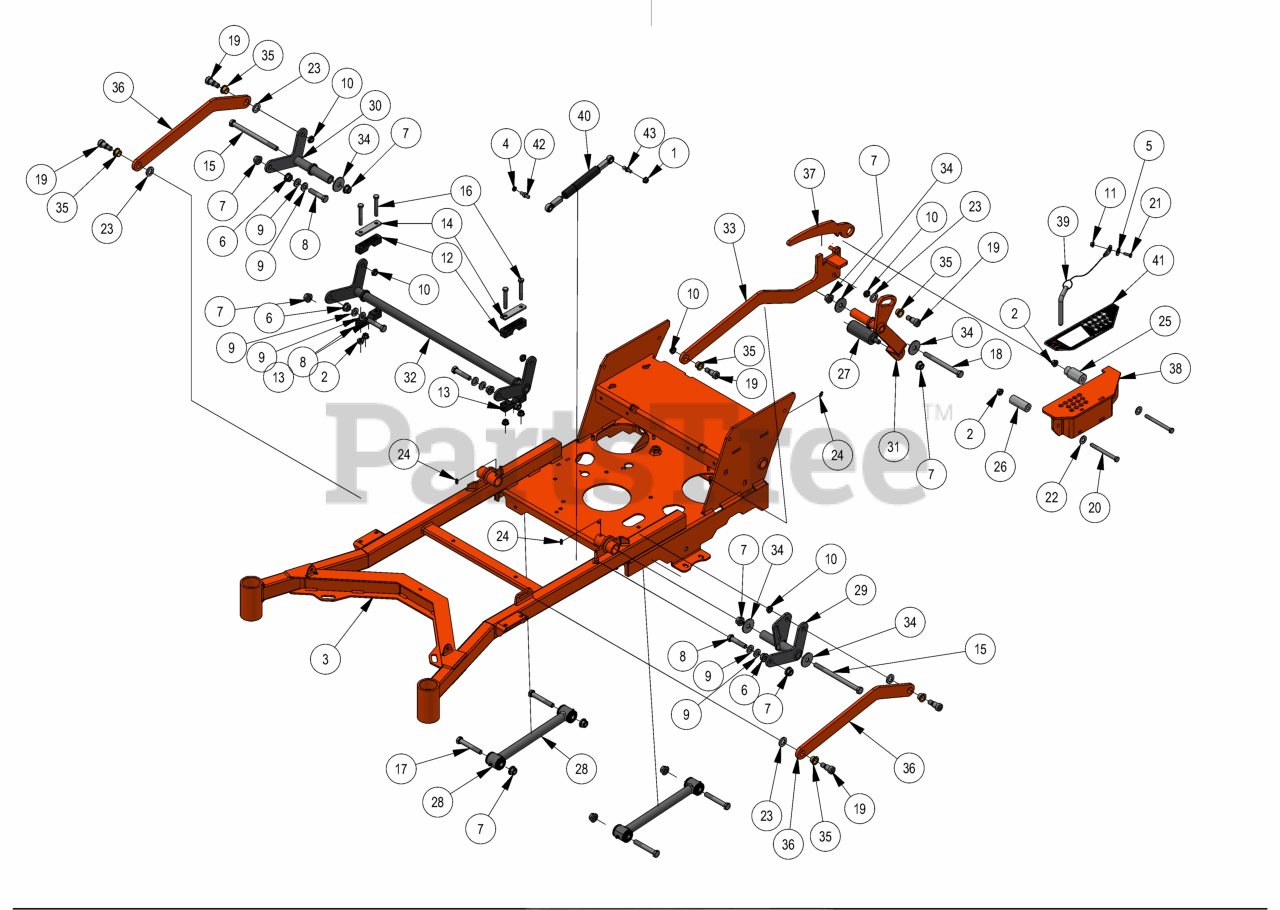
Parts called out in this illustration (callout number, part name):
1	5/16-18 NYLON INSERT FLANGE LOCKNUT ZINC
2	3/8-16 NYLON INSERT FLANGE LOCKNUT (GR.F) ZINC
3	2023 Walk Frame
4	5/16-18 NYLON INSERT JAM LOCKNUT ZINC
5	5/16 USS FLAT WASHER (7/8 OD) ZINC
6	1/2-13 HEX SERRATED FLANGE NUT HARD/ZINC
7	1/2-13 NYLON INSERT FLANGE LOCKNUT ZINC
8	1/2-13 X 2-1/4 HEX CAP SCREW (GR.5) ZINC
9	.505 ID X 1.000 OD X .125 THICK FLAT WASHER NYLON
10	1/2-13 NYLON INSERT JAM LOCKNUT ZINC
11	1/4-20 NYL INSERT FLANGE LOCKNUT ZINC
12	Pillow Block MZ
13	Pillow Block MZ female
14	Pillow Block Strap
15	1/2-13 X 7 HEX CAP SCREW (GR.5) ZINC
16	3/8-16 X 2-1/2 HEX CAP SCREW (GR.5) ZINC
17	1/2-13 X 3-1/4 HEX CAP SCREW (GR.5) ZINC
18	1/2-13 X 5 1/2 HEX CAP SCREW (GR.5) ZINC
19	5/8 X 5/8 SOCKET SHOULDER BOLT ZINC YELLOW
20	3/8-16 X 4 HEX CAP SCREW (GR.5) ZINC
21	1/4-20 X 3/4 HEX CAP SCREW (GR.5) ZINC
22	3/8 FLAT WASHER USS (1" OD) ZINC
23	.635 ID X 1.120 OD X .140 THICK FLAT WASHER NYLON
24	1/4 DRIVE-TYPE STRAIGHT GREASE FITTING (NO BALL) ZINC YELLOW
25	Stand On Spacer 2.5'' With shoulder
26	Stand On Spacer 2.5''
27	Knurled Pedal
28	Hybrid Turnbuckle/Deck Locator
29	23WB Right Rear Actuator
30	23WB Left Rear Actuator
31	23WB Foot Pivot weldment
32	23WB Actuator bar
33	23WB Deck Height Lever weldment
34	.520 ID X 1.750 OD X .120 THICK FLAT WASHER ZINC
35	.627 ID X .753 OD X .500 LGTH X 1.000 FLG OD X .094 FLG THICK FLANGED BEARING OIL-IMPREG BRNZ
36	23WB Actuator link V
37	23WB Deck Lever Lock V2
38	23WB deck height indicator weldment V3 4.27
39	2023 stand on Height Adj Pin
40	200 lb Gas Spring- 54" Deck outlaw
41	2023 WB Deck Height Decal
42	10mm Damper Ball Stud-Steering
43	10mm Damper Ball Stud-XP Linkage
